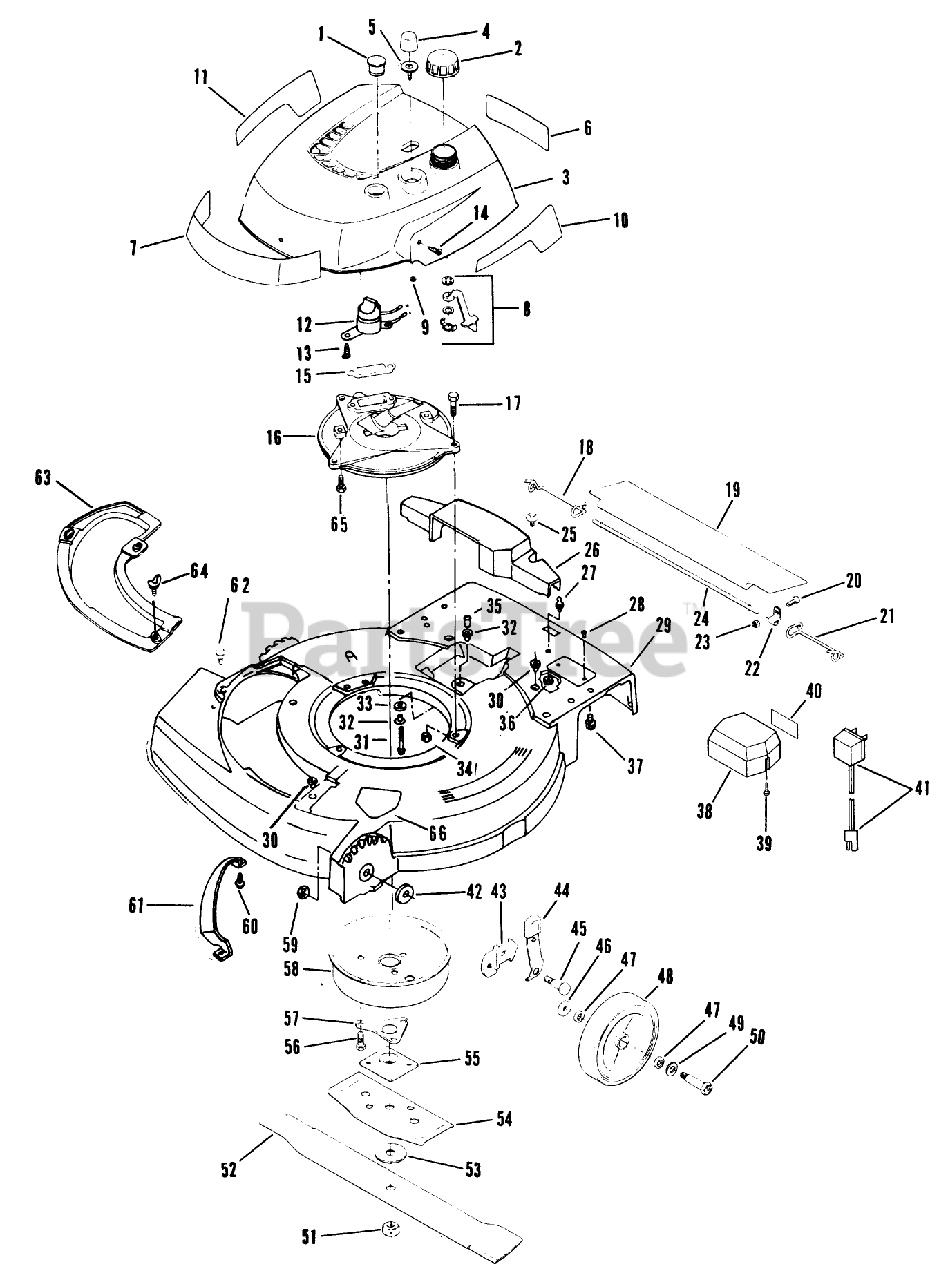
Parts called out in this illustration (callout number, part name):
6	Decal-Instructions
9	LOCKNUT S
14	SCREW S
15	Gasket-Exhaust
17	SCREW
18	SPRING;TRAILING SHIELD RH
19	SHIELD
21	SPRIG T/SHLD ASOC
22	CLAMP ROD KMC
23	LOCKNUT E
24	ROD 21" ADVANCE
25	SCREW SEMS TRM HEX HD
32	SPACER ECK PRES
33	GROMMET
34	NUT-LOCK F
35	SPACER
37	SCREW
42	WASHER
46	WASHER WROUGHT
47	WASHER
48	WHEEL & TIRE KIT
49	SPACER
50	BOLT WHEEL
51	NUT-BLADE
53	WASHER
55	PLATE AND COLLAR ASM
56	SCREW
57	SUPPORT F
59	LOCKNUT
61	BAR-TOE
64	WING SCREW LAWRE
65	SCREW V
